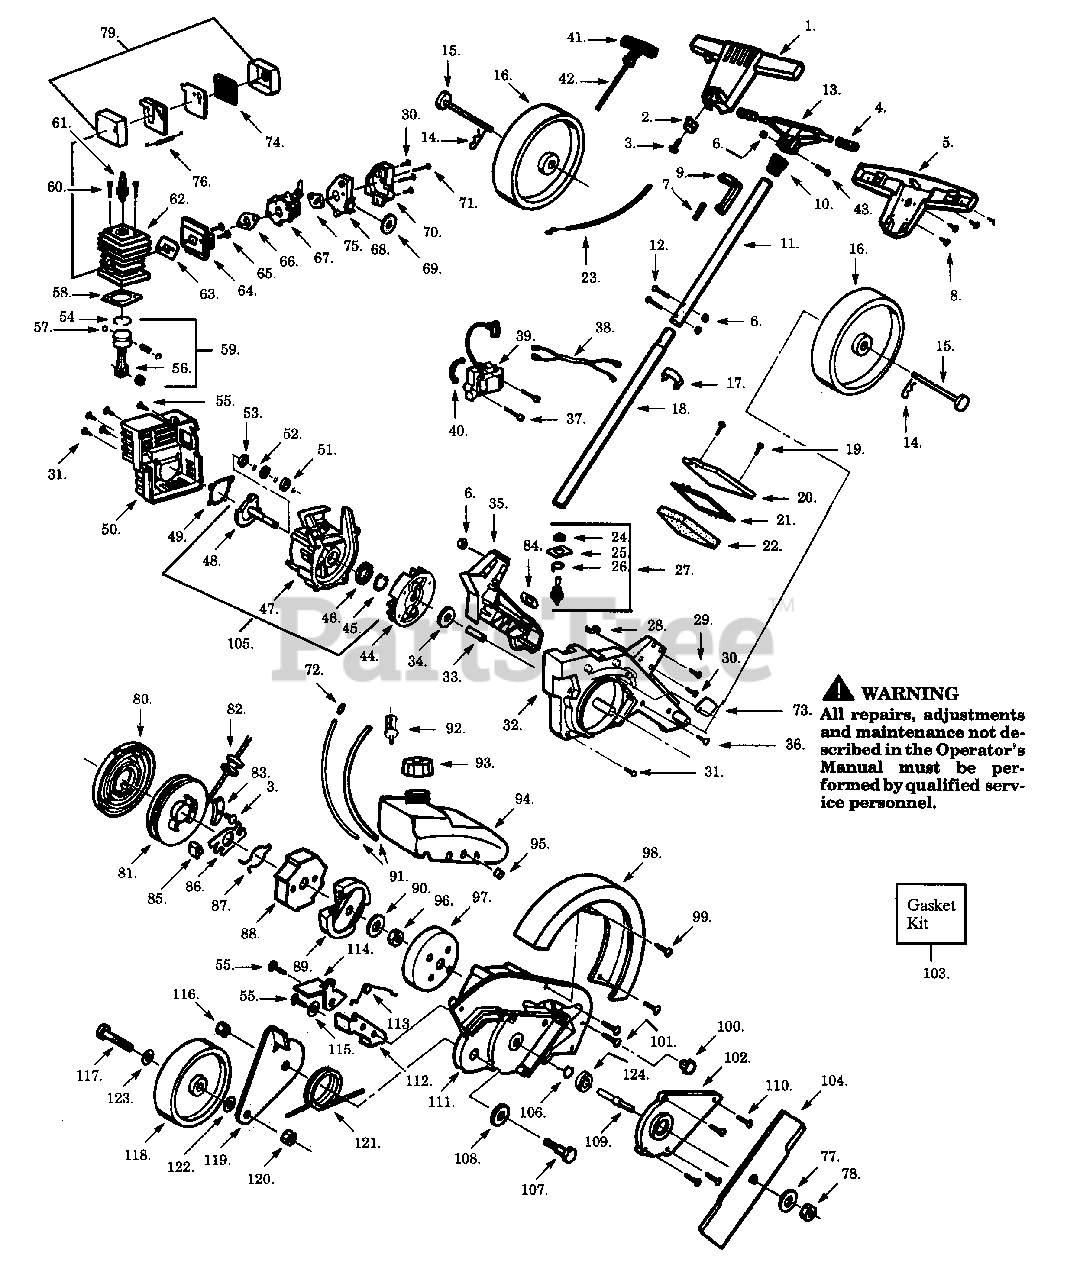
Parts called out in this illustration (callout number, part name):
1	Upper Handle
2	Handle Eyelet
3	Screw-Eyelet
4	Spring Isolator
5	Lower Handle
6	Locknut-Coupling/Shaft
7	Throttle Spring
8	Screw-Handle
9	Throttle Trigger
10	Handle Spring
11	Upper Handle Tube
12	Screw-Shaft
13	Coupling-Handle
14	Bridgepin
15	Axle Pin
16	Rear Wheel
17	Tube Clamp
18	Lower Handle Tube
19	Screw-Filter Cover
20	Type 1 & 2
22	Air Filter Foam
23	Throttle Cable
24	Boot w/Nut
25	Switch Indicating Plate
26	Grounding Terminal
27	Switch Grounding Assy
28	Speed Nut
29	Screw-Fan Housing
30	Screw-Fan Housing
31	Screw-Fan Housing/Shroud
32	Type 1 & 2
32	Type 3 (Kit - Incl. 73 & 101)
33	Flywheel Spacer
35	Axle Cover
36	Screw-Fan Housing
37	Screw-Ignition Module
38	Switch Wire Ass'y.
39	Ignition Module
40	Spacer-Ignition Module
41	Starter Handle
42	Rope Kit
43	Screw-Coupling
44	Flywheel Ass'y.
45	Retaining Ring-C'case
46	C'case Seal
47	Crankcase Ass'y.
48	Crankshaft Ass'y.
49	Gasket-Crankcase
51	Outer Bearing
52	Retaining Ring-C'shaft
53	Inner Bearing
54	Piston Ring
55	Screw-Shroud
56	Connecting Rod Ass'y.
57	Piston Pin Retainer
58	Gasket-Cylinder
59	Piston Kit
60	Screw-Cylinder
61	Spark Plug (RCJ-8Y)
62	Cylinder Kit
63	Gasket-Cylinder/Carb Adaptor
64	Carb. Adaptor
65	Screw-Carb Adaptor
66	Carb. Gasket
67	Type 1 & 2 (WT-242)
67	Type 3 (WT 308)
68	Air Box Base
69	Foam Seal
70	Airbox Cover
71	Screw-Airbox Cover
72	Fuel Line Fitting
73	Fuel Line Retainer
74	Muffler Screen
75	Gasket-Carb.
76	Muffler Spring
77	Washer-Blade
78	Nut-Blade
79	Muffler Kit
80	Starter Spring
81	Starter Pulley Kit
83	Rope Retainer
84	Gasket-Tube
85	Starter Dog
86	Starter Cam
87	Starter Dog Wire
88	Starter Cup
89	Clutch Ass'y.
90	Washer-Belleville
91	Fuel Line Kit
92	Fuel Pick-up Ass'y.
93	Fuel Cap Ass'y.
94	Fuel Tank Ass'y.
95	Fuel Tank Isolator
97	Drum Clutch
98	Front Shield
100	Dustplug
101	Screw-Bearing Holder
102	Type 2 & 3
103	Gasket Kit
105	C'case & C'shaft Ass'y.
106	Retainer Ring
107	Shoulder Bolt
109	Drive Shaft
111	Gear Box Ass'y.
112	Back Plate
114	Height Lever
115	Retainer-Starter Pulley
116	Nut-Swing Arm
117	Bolt-Front Wheel
118	Front Wheel
119	Swing Arm
120	Locknut-Swing Arm
121	Front Axle Spring
122	Washer-Thrust
123	Washer-Flat
124	Washer-Thrust
